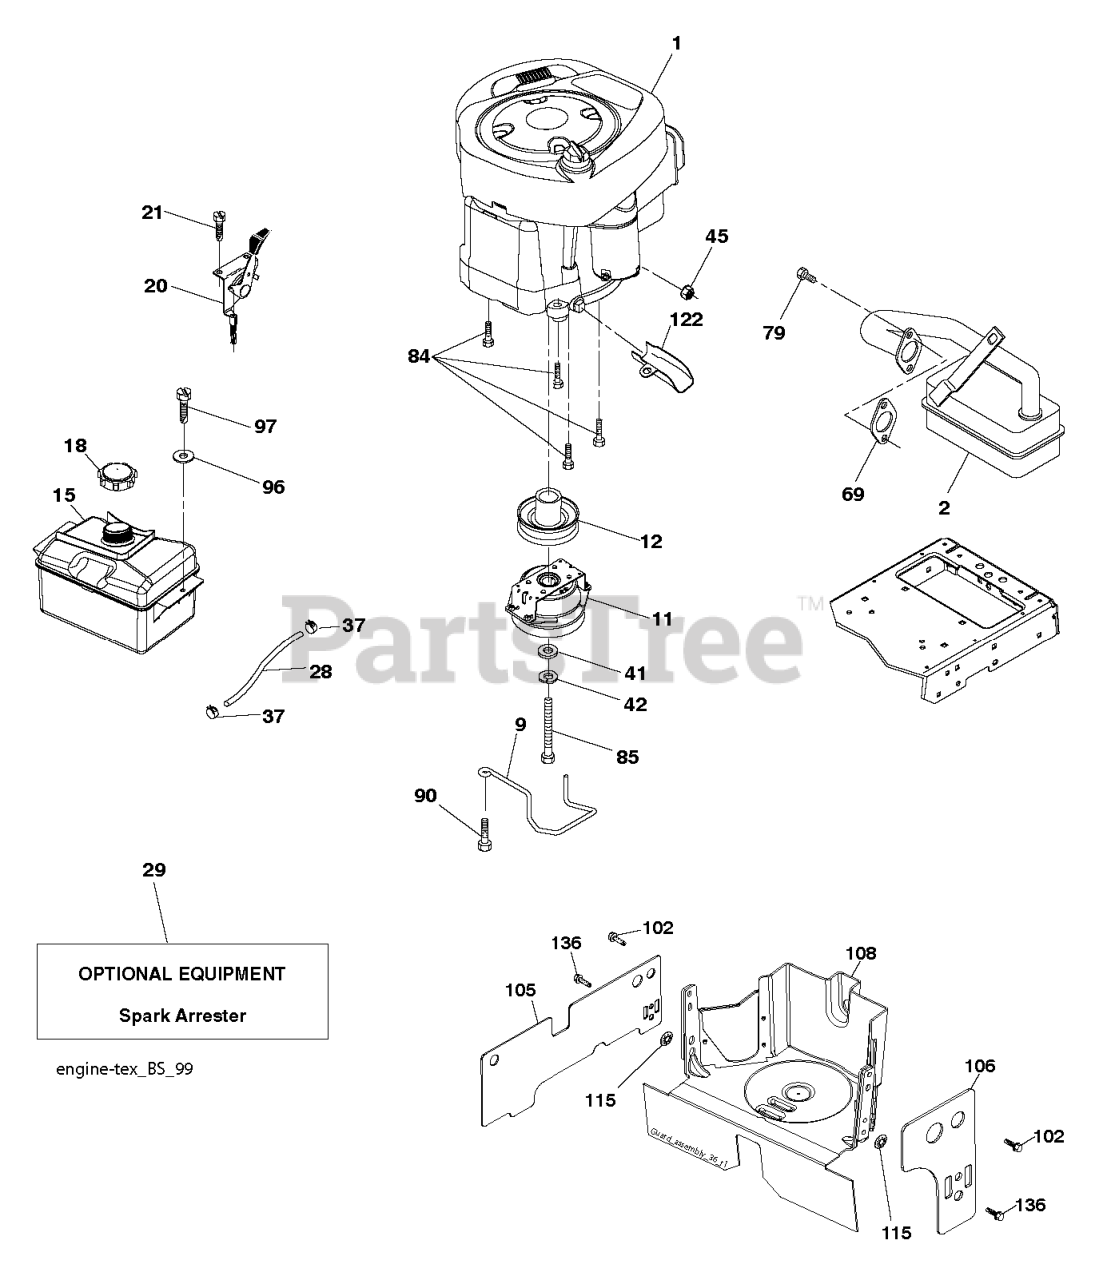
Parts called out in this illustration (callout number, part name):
2	MUFFLER.B&S.MODEL.21.11HP.OHV
9	KEEPER.BELT.ENGINE.3.25 (3 2)
11	RB.CLUTCH.OGURA.4.4.PD
12	PULLEY.ASM.ENG.OGURA.3
15	RP TANK FUEL FRT 1.5 GAL
18	CAP ASM.FUEL.2.25"FR.
20	CONTROL.TH/CK.C.
21	SCREW.#10 X 0.750.BOS
28	LINE.FUEL.20
29	KIT.SPARK ARRESTOR 794945 B&S
37	HOSE CLAMP
42	LOCKWASHER
45	NUT
69	REPL BY 532 27 22-93
79	SCREW.SOCKET HD.5/16-1
84	SCREW.3/8-16
85	BOLT HEX 7/16-20X4-1/4"
90	SCREW 3/8-16X1
96	WASHER
97	SCREW HEXWSHR 1/4-20X3/4
102	SCREW
105	SHIELD LEFT
106	SHIELD SIDE
108	COVER PULLEY
115	PALNUT 1/4
122	EXTENSION DRAIN OIL
136	SCREW.1/4-20X5/8
